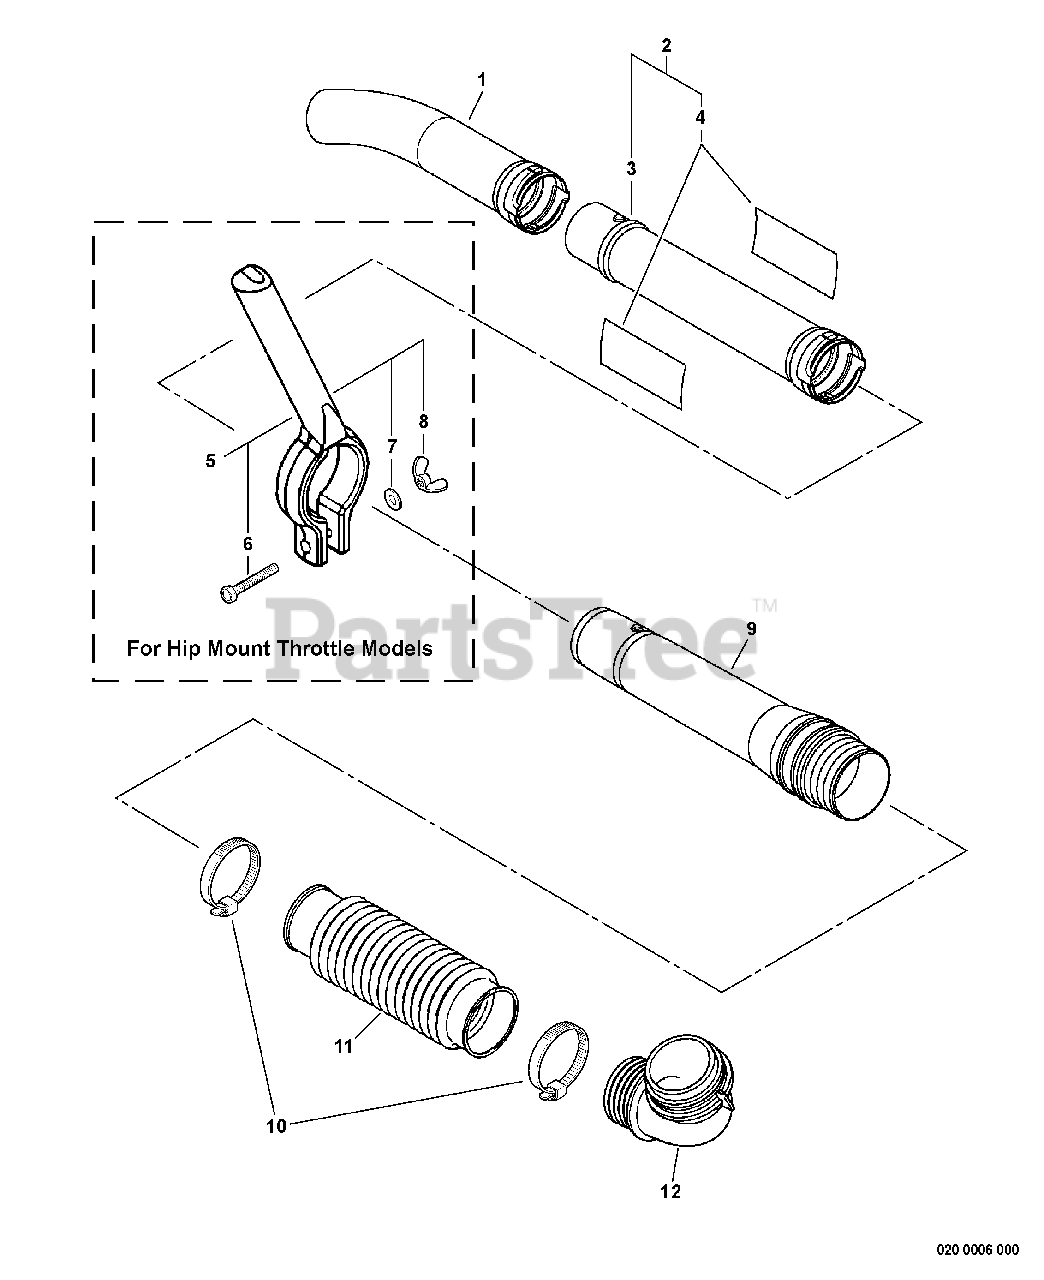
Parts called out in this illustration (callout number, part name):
1	TUBE, BLOWER - CURVED
2	BLOWER TUBE KIT - STRAIGHT
3	TUBE, BLOWER - STRAIGHT
4	LABEL, ECHO BLOWER TUBE
5	HANDLE ASSY
6	BOLT 6×45
7	WASHER 6.5×11.5×0.8
8	NUT, WING 6
9	TUBE, SWIVEL
10	CLAMP 58.7 MM / 82.5 MM
11	TUBE, BLOWER - FLEXIBLE
12	TUBE, BLOWER - ELBOW
